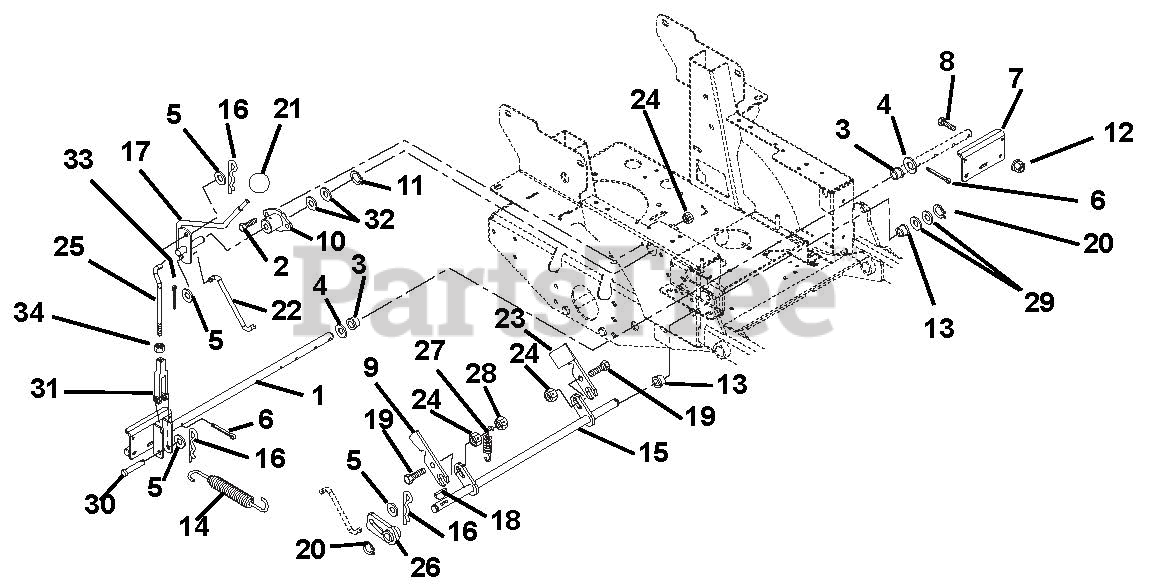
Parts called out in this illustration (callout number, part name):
1	Weldment, Brake Shaft
2	Bolt, Hex .31-18 x 1.00 Grade 5
3	Bushing, Flange .762 x 1.00 x .58 x 1.48 Nylon
4	Washer, Flat Steel .755 x 1.375 x .062
5	Washer, Flat Steel .406 x .812 x .065
6	Pin, Cotter .12 x 1.00 Extended Prong Square Cut
7	Paddle, Brake
8	Bolt, Hex .25-20 x 1.5 Grade 5
9	Slide, Interlocking Brake
10	Bushing, Flange
11	Ring, Retaining External .625 x .05
12	Nut, Nyloc Flange .25-20
13	Bushing, Flange .515 x .75 x .745 x 1.00
14	Spring, Engine Transmission
15	Weldment, Mechanical Brake
16	Pin, Hair
17	Weldment, Brake Actuating
18	Key, Woodruff .13 x .63
19	Bolt, Round Head Square Neck .31-18 x 1.25 Grade 5
20	Ring, Retaining External .50 x .05
21	Knob, Steering Lock
22	Linkage, Brake Actuating
23	Interlock, Safety Switch
24	Nut, Nyloc Flange 5/16-18
25	Linkage, Brake Compact-Z
26	Weldment, Parking Brake Hub
27	Spring, Tension .061 x .50 x 3.0
28	Nut, Locking Center .31-18
29	Washer, Flat Steel .505 x 1.00 x .062
30	Pin, Clevis .37 x 1.75
31	Clevis, .38-24 Adjustable Swivel
32	Washer-Flat-Steel .630 x 1.250 x .062
33	Pin, Cotter .09 x .75 Extended Prong Square Cut
34	Nut, Jam .375-24
